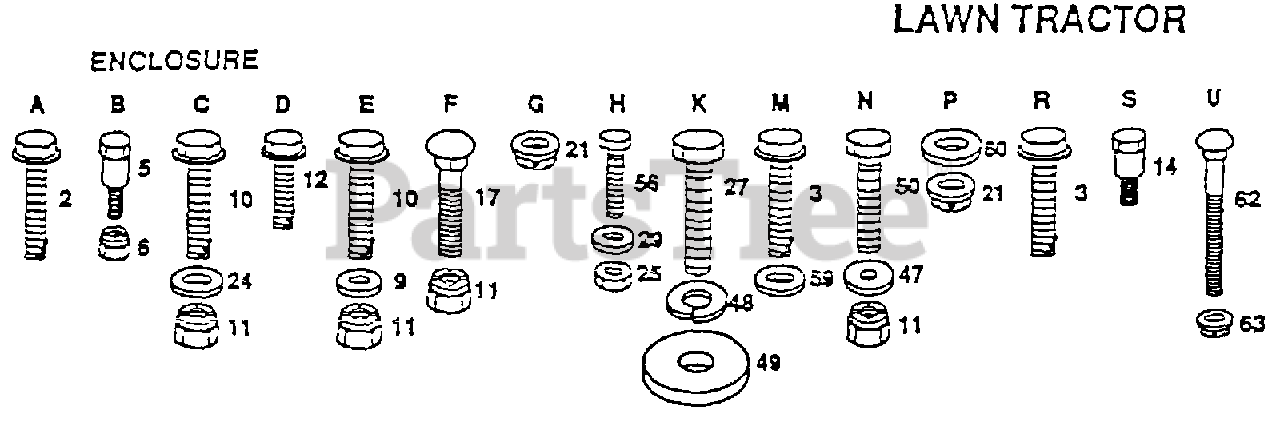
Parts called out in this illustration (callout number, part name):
2	SCREW
3	SCREW GTV
9	WASHER
12	SCREW LT
17	BOLT
21	PAL NUT LT
24	WASHER
25	NUT
27	BOLT
47	WASHER
48	LOCKWASHER
49	WASHER
50	BOLT
56	SCREW SPECIAL
59	WASHER
60	WASHER PM
62	BOLT
